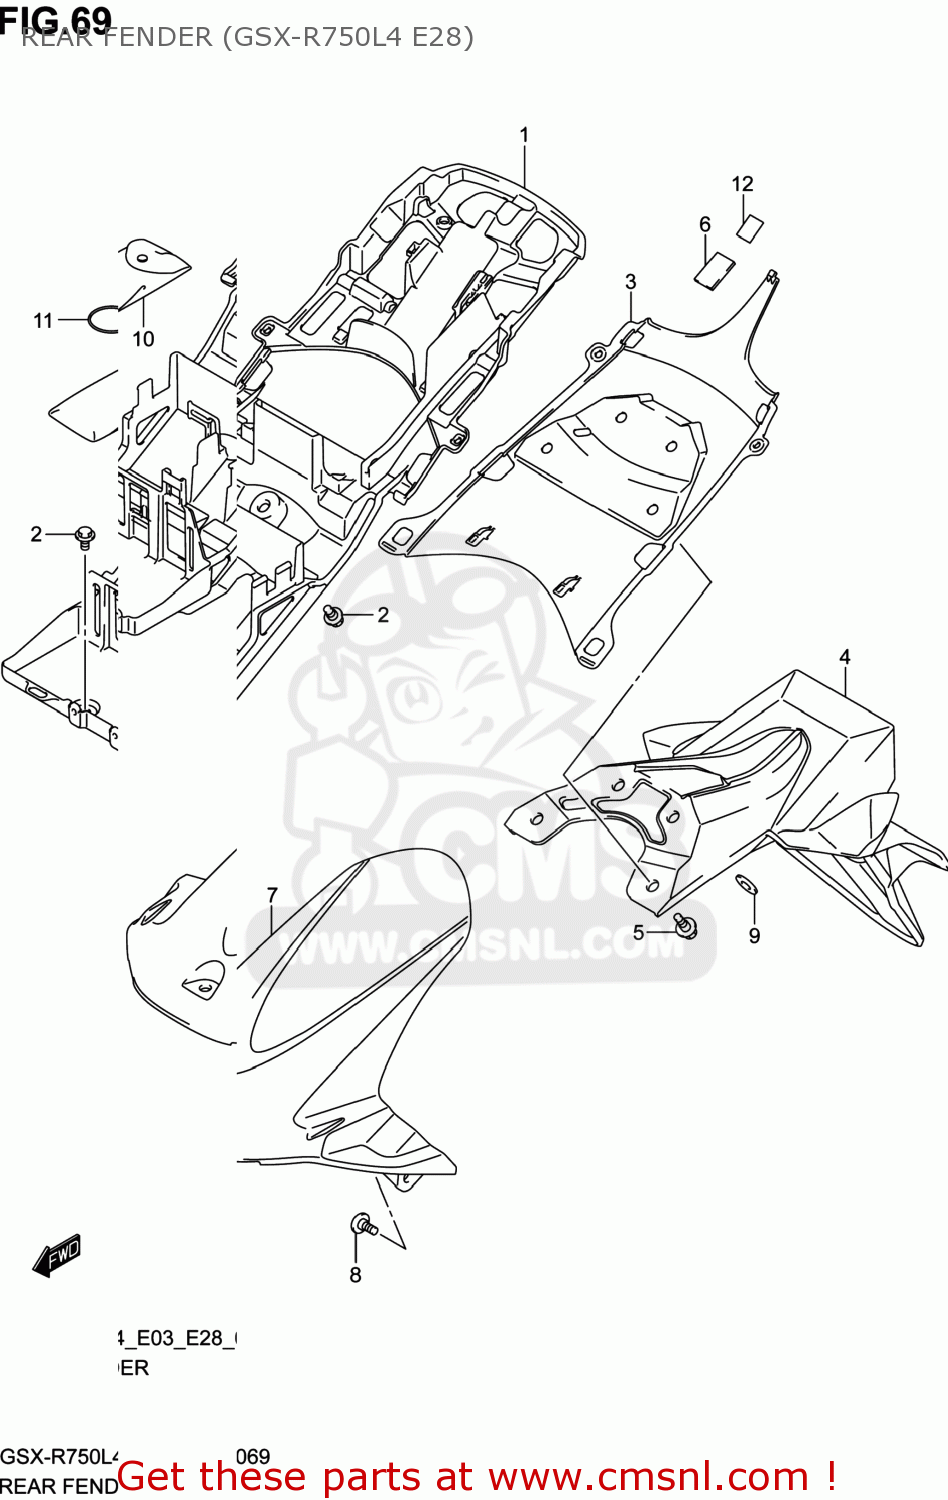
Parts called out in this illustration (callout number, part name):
1	FENDER,RR FR
2	BOLT(6X12)
3	COVER,RR FENDER FR
4	FENDER,RR RR
5	BOLT(6X17.8)
6	CUSHION,FUEL TANK ATTACHMENT
7	FENDER,RR LWR
8	SCREW(6X16)
9	WASHER(6.5X20X1.2)
10	TOOL ASSY
11	O RING(D:3.5,ID:56.5)
12	FASTENER,COWLING
